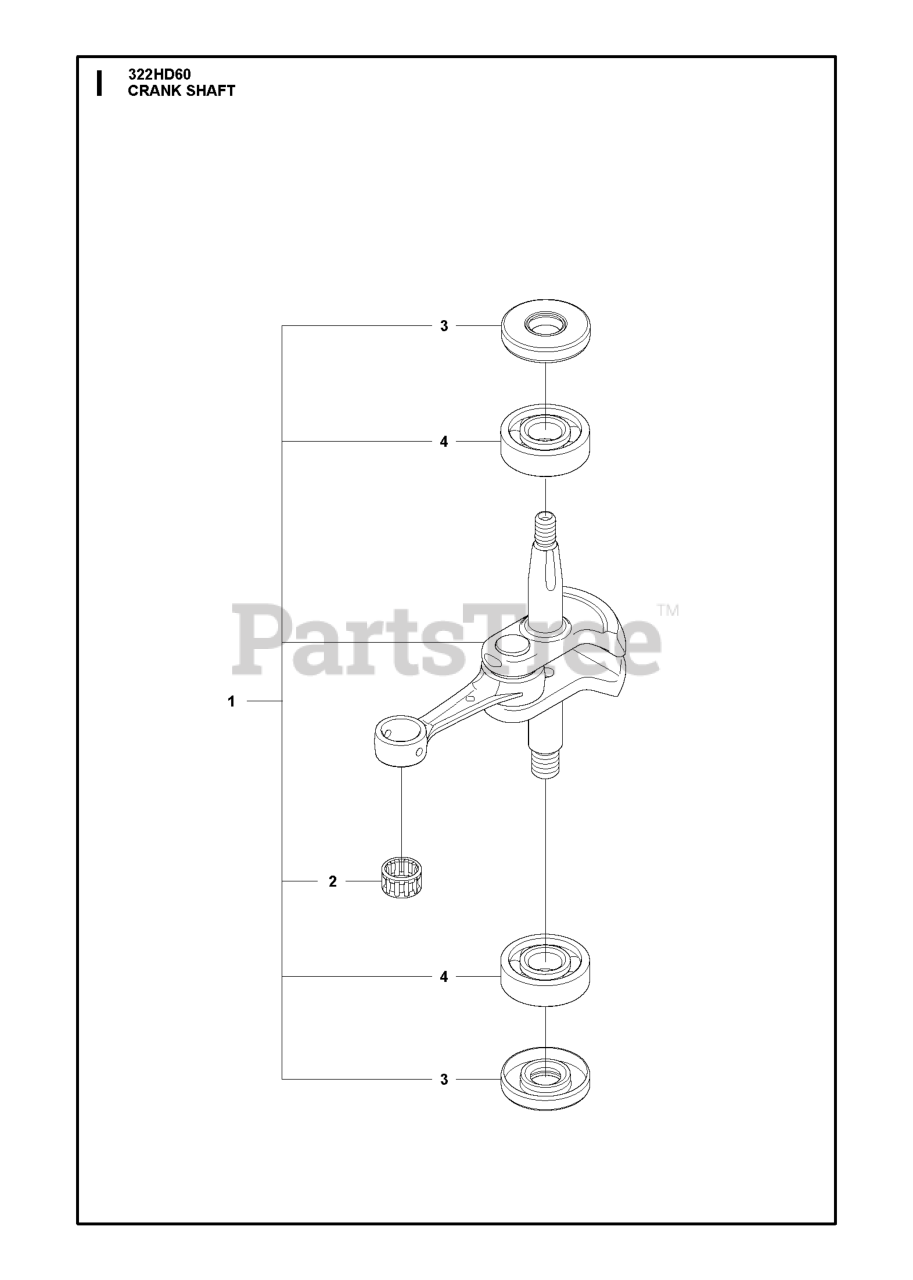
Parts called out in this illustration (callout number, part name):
1	CRANKSHAFT KIT
2	NEEDLE BEARING
3	SEALING RING
4	BALL BEARING
